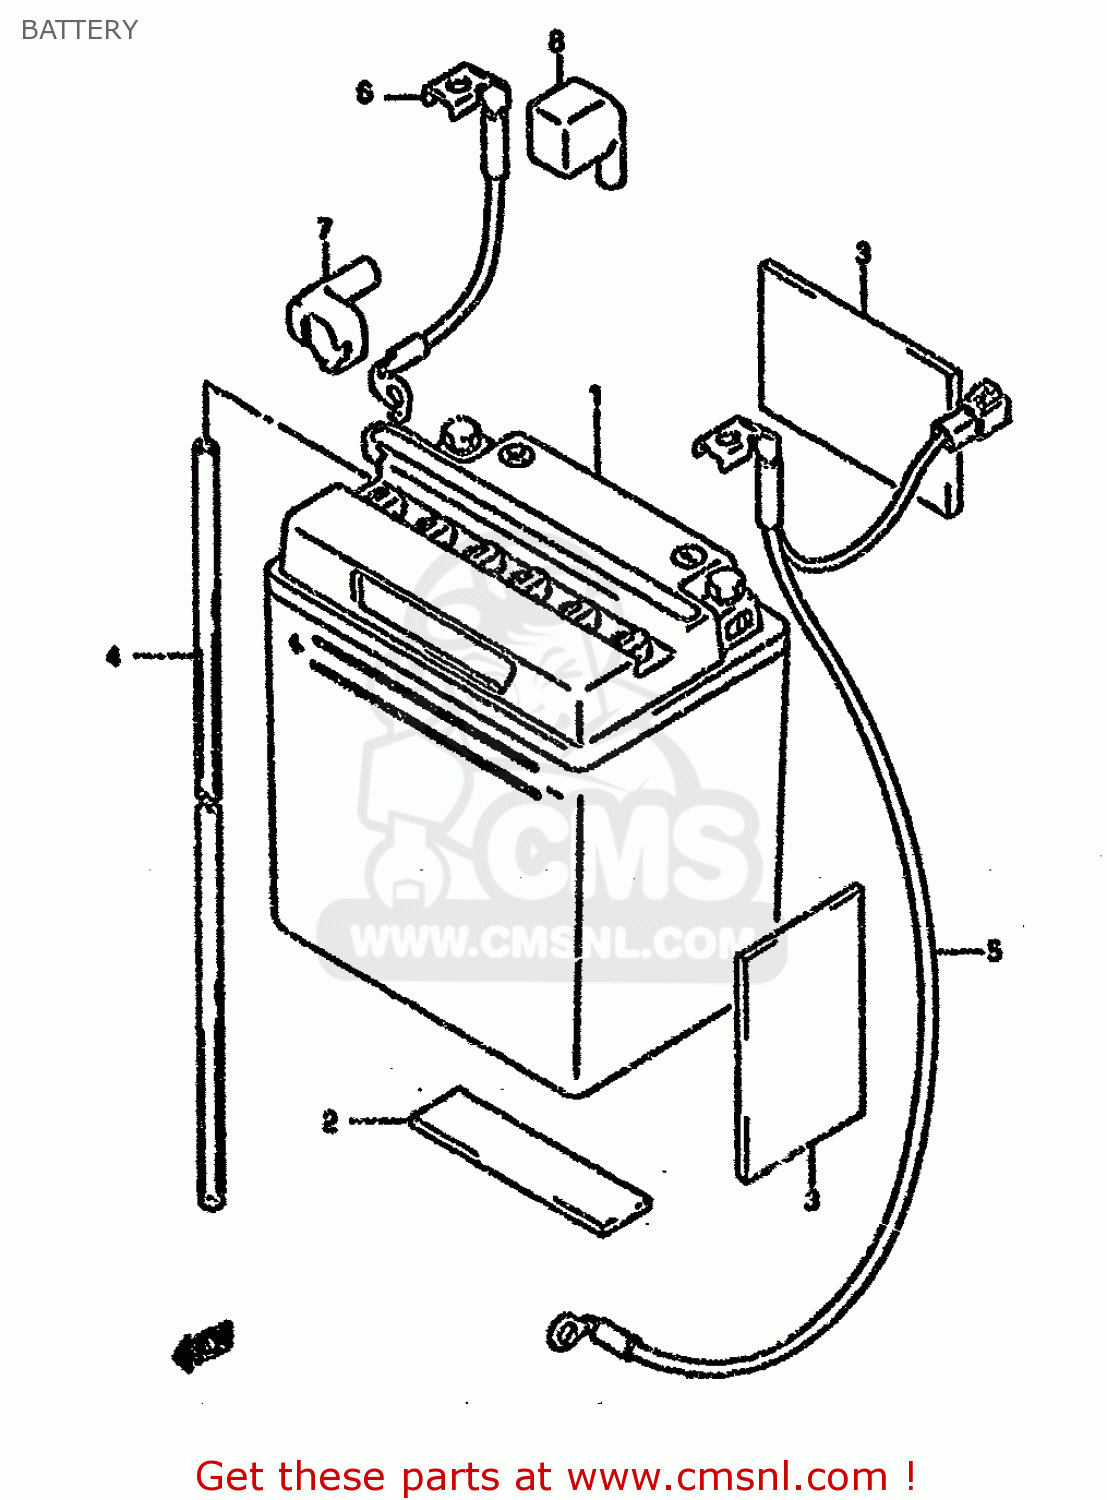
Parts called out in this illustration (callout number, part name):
1	BATTERY ASSY (12V)
2	CUSHION,BATTERY(80X27X3)
3	CUSHION
4	HOSE,BATTERY EXHAUST(L:780)
5	WIRE,BATTERY MINUS LEAD
6	WIRE,BATTERY PLUS LEAD
7	CAP,STARTER RELAY TERMINAL
8	CAP,BATTERY PLUS TERMINAL
